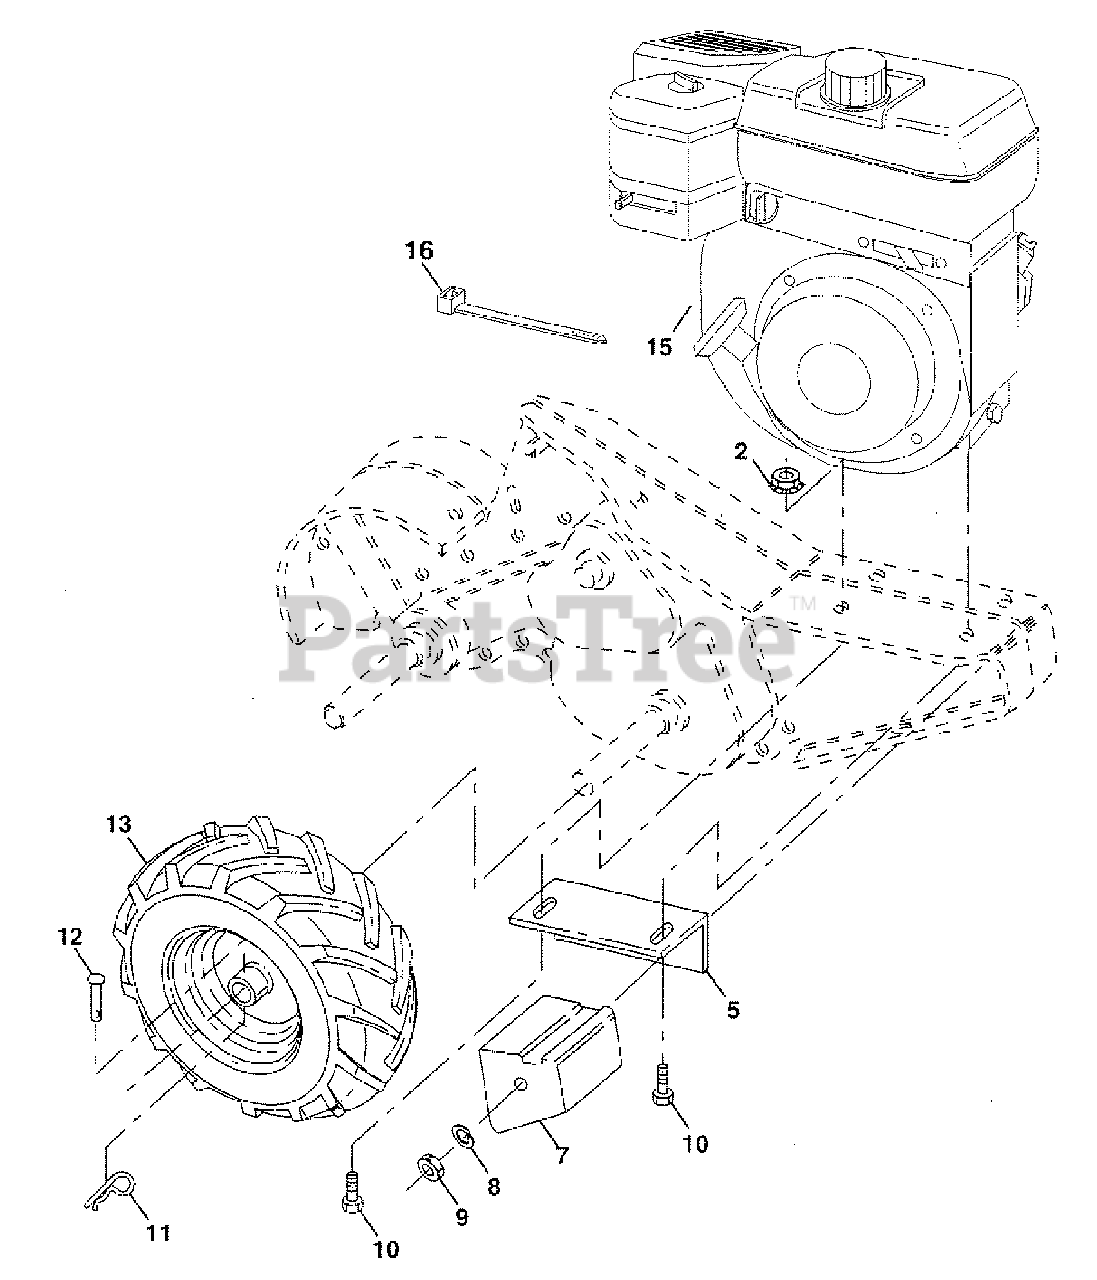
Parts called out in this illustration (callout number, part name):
2	Nut, Lock Hex Flg
5	Bracket, Reinforcement
7	Counter Weight, R.H.
8	Washer, Lock 3/8
9	Nut, Hex 3/8-16
10	Bolt, Hex 5/16-18x1-1/2
11	Clip, Hairpin
12	Rivet, Drilled
13	Tire
13	Tire Valve
15	Engine, Briggs Model 110402 (Orderpartsfrom engine manufacturer)
